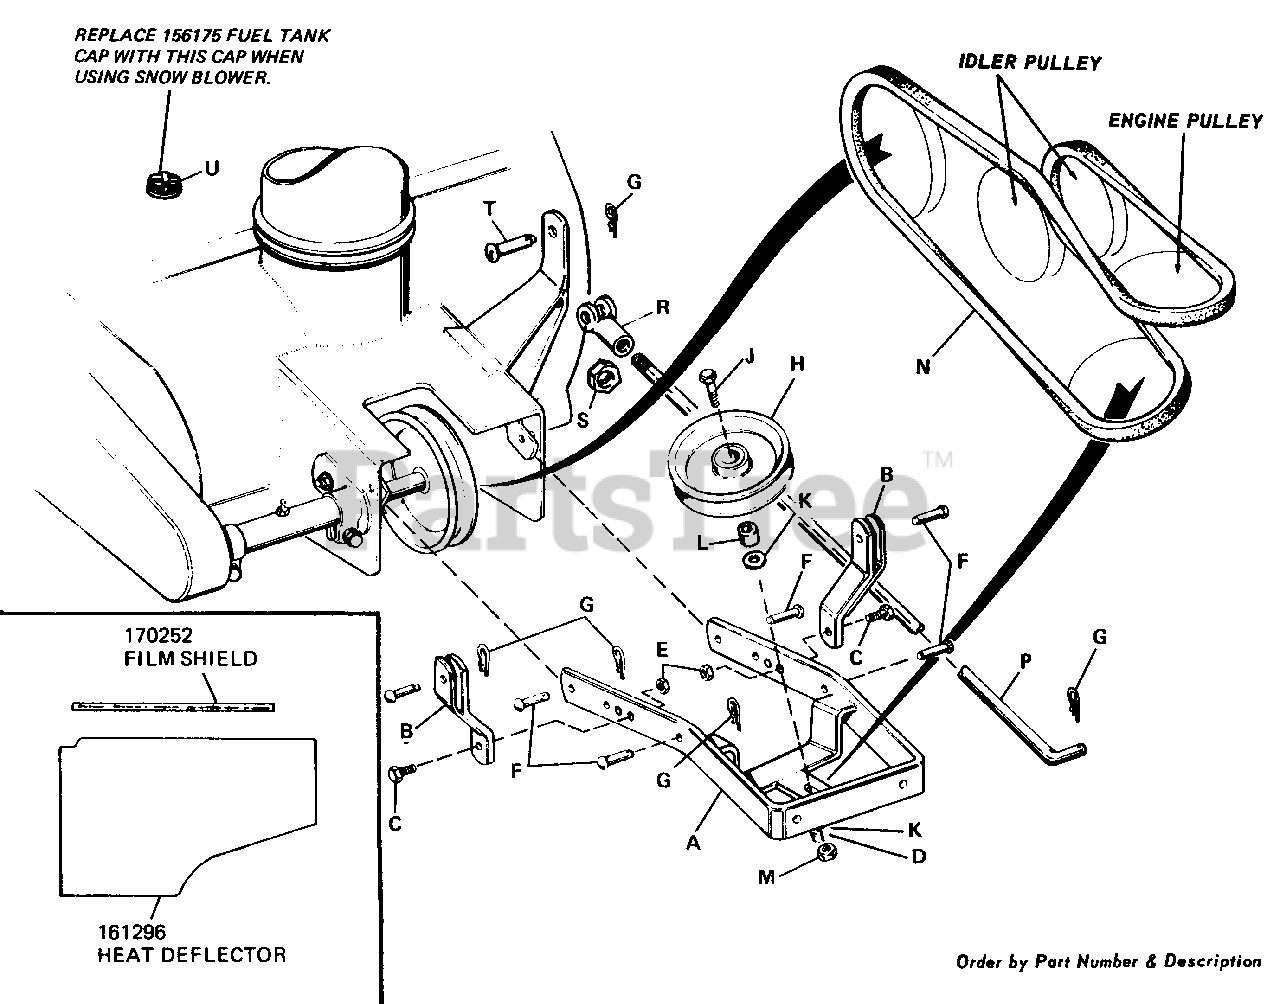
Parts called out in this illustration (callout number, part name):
A	Push Arm Assembly
B	Support Arm Assembly
C	Hex. Capscrew, 3/8"-16 x 1" lg.
D	Lock Washer, 3/8"
E	Hex. Nut, Full Lock, 3/8"-16
G	Spring Clip
J	Hex. Capscrew, 3/8"-16 x 1-3/4" lg.
K	Plain Washer, 3/8"
M	Hex. Nut, Full, 3/8"-16
P	Front Lift Rod
R	Adjusting Yoke
S	Hex. Nut, Full, 1/2"-20
U	Cap (Winter) Fuel Tank
